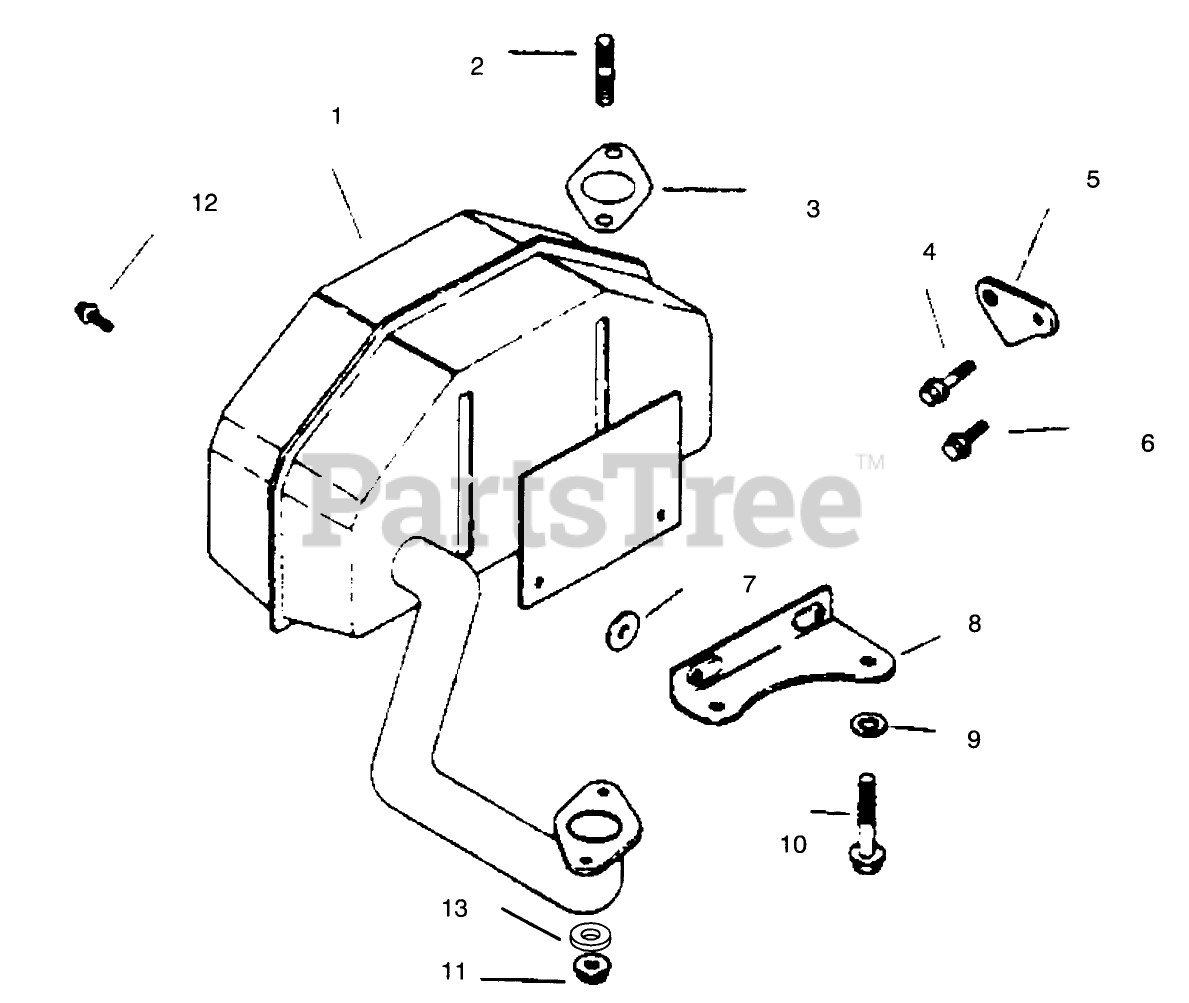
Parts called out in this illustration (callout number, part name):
1	Muffler
2	Stud
3	Gasket-Exhaust
4	Screw
5	Strap-Lifting
6	Screw
7	Washer
8	Bracket-Muffler
9	Washer
10	Screw
11	Nut
12	Screw
13	WASHER-LOCK
